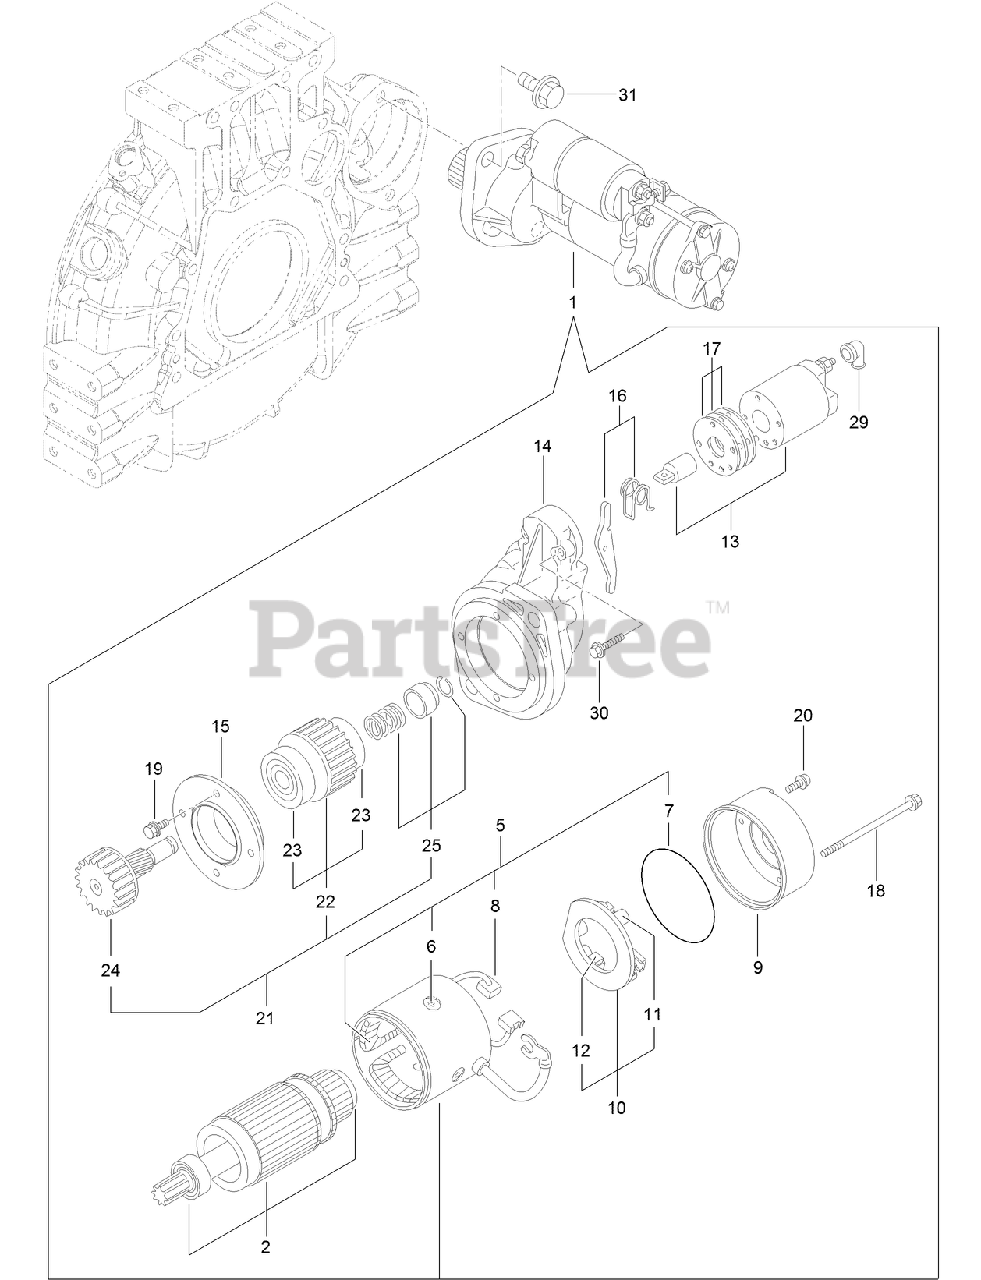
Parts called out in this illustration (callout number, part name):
1	STARTER
2	ARMATURE ASM
5	FIELD COIL ASM
7	O-RING
10	BRUSH HOLDER ASM
11	SPRING
13	SWITCH ASM
14	CASE-GEAR
15	RETAINER
16	LEVER SET
17	DUST COVER ASM
18	BOLT-THROUGH
21	PINION ASM
22	CLUTCH ASM
23	BEARING-BALL
25	STOPPER KIT
29	COVER-TERMINAL
